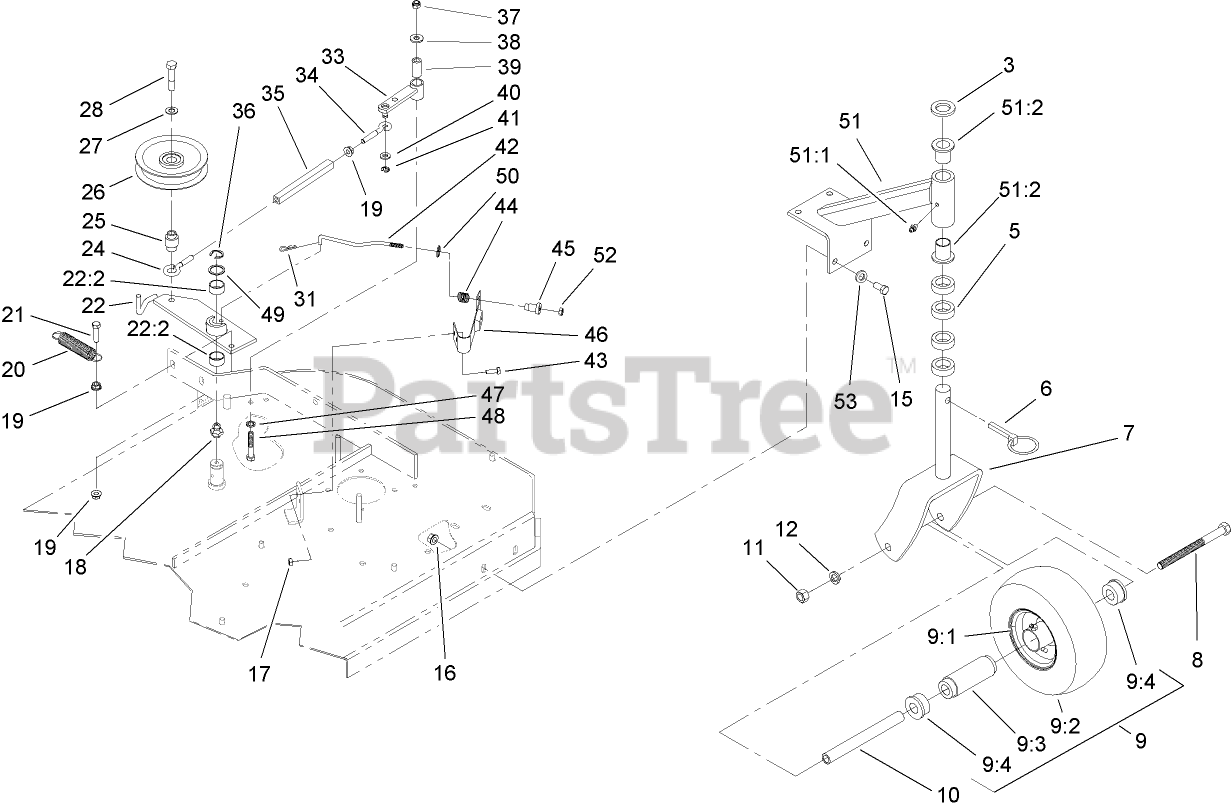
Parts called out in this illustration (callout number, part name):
3	WASHER-FLAT
5	SPACER-CASTER
7	FORK
8	SCREW-HH
9	WHEEL AND TIRE ASM
9:1	Rim
9:3	BEARING
9:4	BUSHING
10	SPACER
11	NUT-HH
12	WASHER-LOCK
15	SCREW-HH
16	NUT-HHF, WHIZ
17	NUT-LOCK, NI
18	FITTING-GREASE
19	NUT-HF
20	SPRING-EXTENSION
21	SCREW-HH
22	Idler Arm ASM
22:2	SLEEVE-BEARING
24	EYEBOLT-THREAD, LH
25	BUSHING-ENGAGEMENT
26	PULLEY-IDLER
27	WASHER-BELLEVILLE
28	SCREW-HH
31	PIN-COTTER
33	ARM-ASSIST
34	EYEBOLT-THREAD, RH
35	BODY-TURNBUCKLE
36	RING-RETAINING, EXT
37	NUT-LOCK, NI
38	WASHER-FLAT
39	TUBE-PIVOT
40	WASHER-PLAIN
41	RING-RETAINING, EXT
42	Rod-Brake
43	SCREW-HH
44	SPRING-COMPRESSION
45	SPACER-FLANGED
46	PAD AND SPRING ASM
47	WASHER-SPRING
48	SCREW-HH
49	WASHER-SPINDLE
50	RING-PUSH ON
51	SUPPORT ASM
51:1	FITTING-GREASE
51:2	BEARING-FLANGED
52	NUT-LOCK, NI
53	WASHER-FLAT
